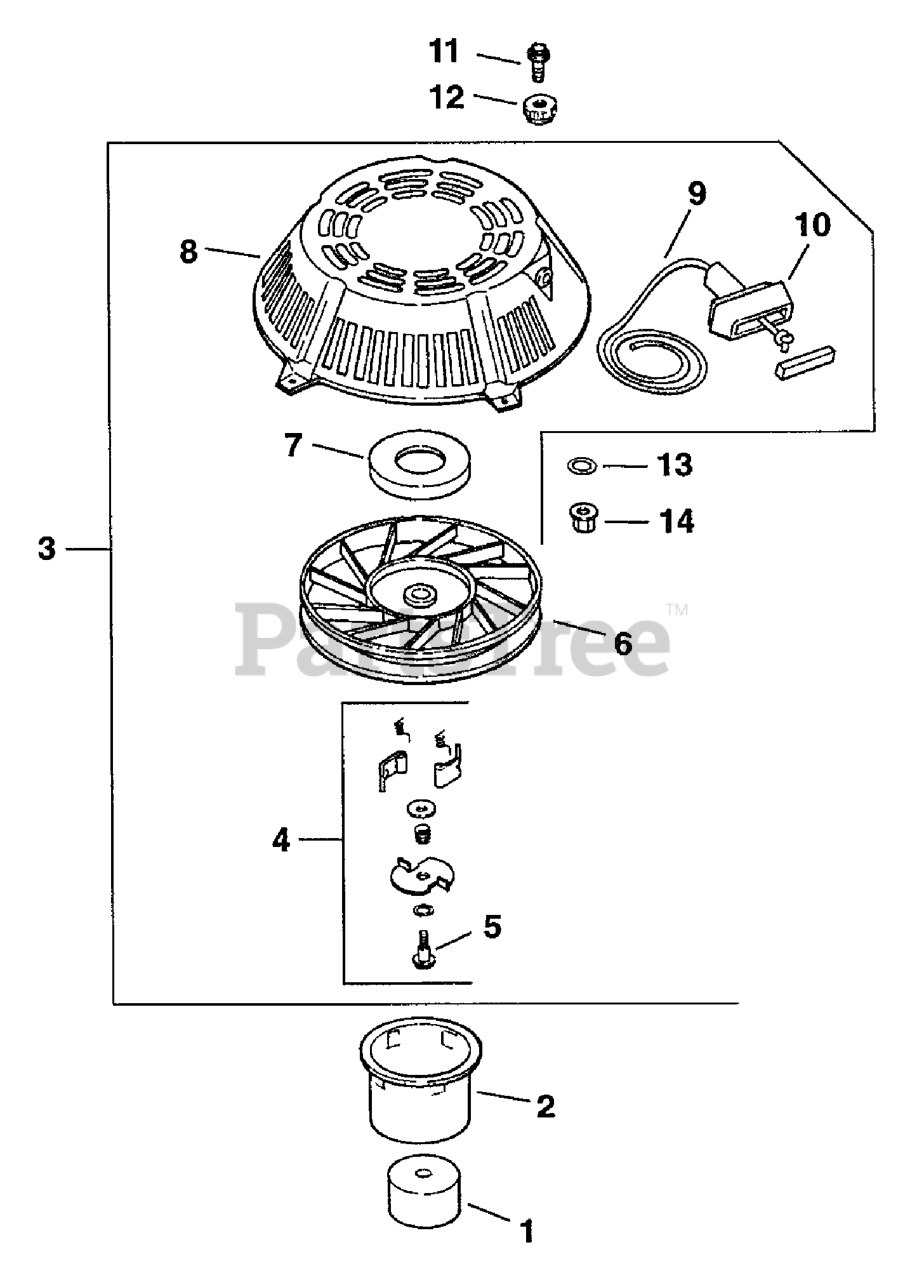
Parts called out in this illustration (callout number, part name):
1	SPACER, DRIVE CUP
3	STARTER, RECOIL USE 24 165 03-S
4	KIT, DOG REPAIR - (#DSC)
5	SCREW - DISCONTINUED
6	PULLEY - (#DSC)
7	SPRING & KEEPER - (#DSC)
8	HOUSING, STARTER
9	ROPE - DISCONTINUED
10	HANDLE - USE 25 166 01
11	SCREW, SPECIAL HEAD
12	NUT, KNURL
13	WASHER, FLAT 1/4" (O.D. 5/8")
14	NUT, 1/4-20 GRADE 2 USE 25 100 20-S
